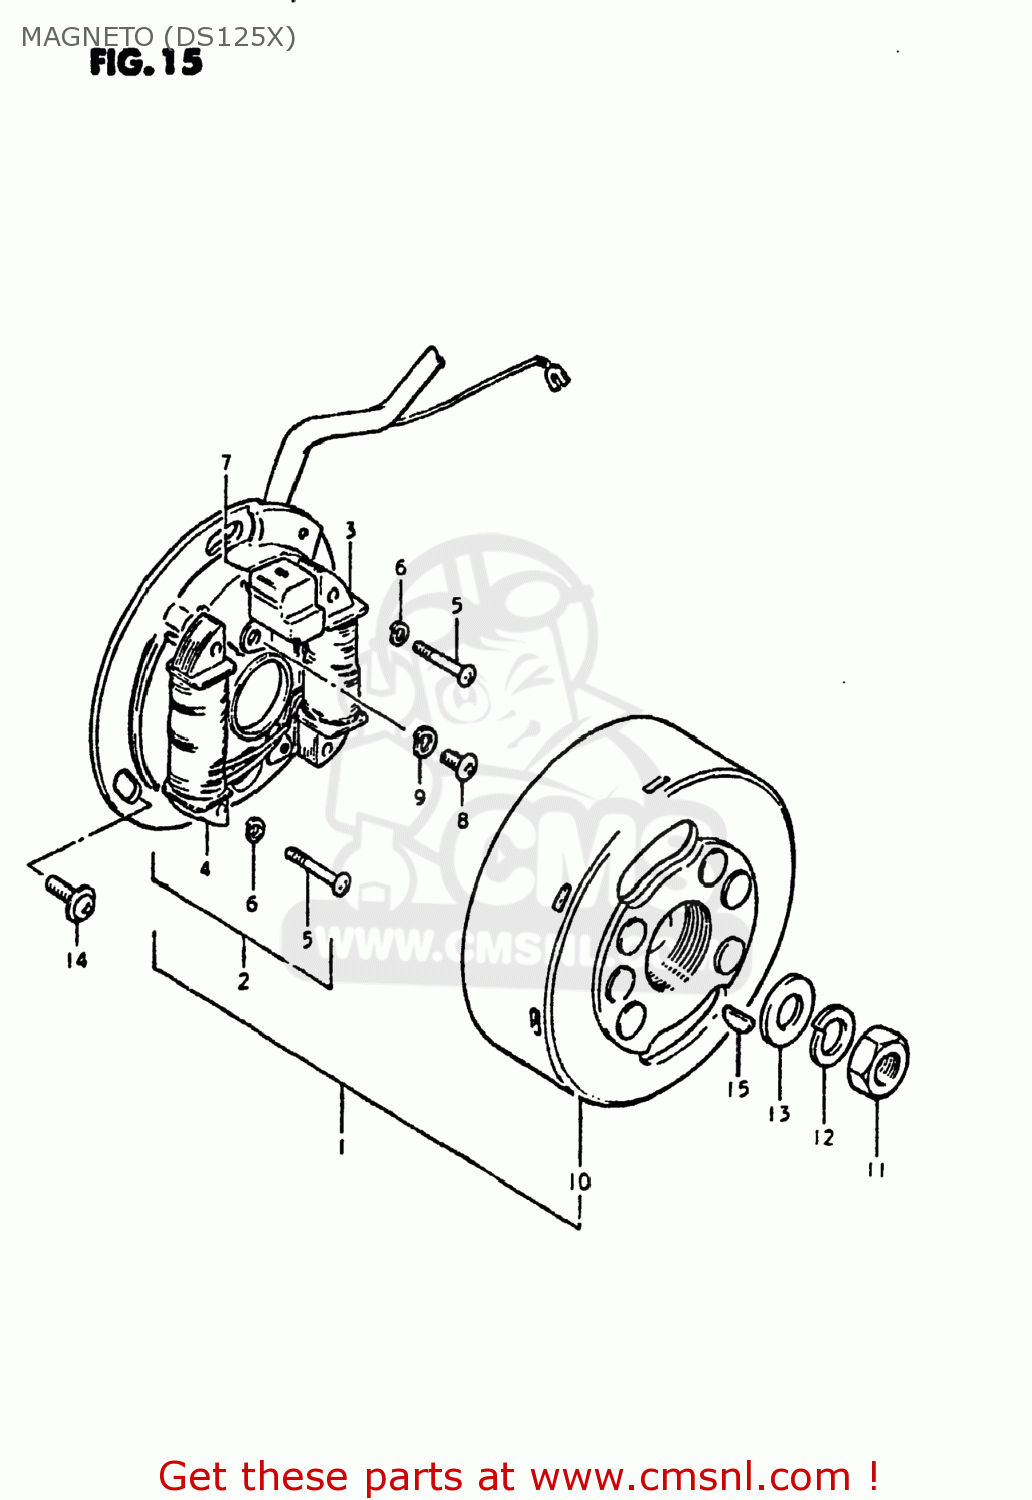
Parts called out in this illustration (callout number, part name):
1	MAGNETO ASSEMBLY
2	STATOR ASSEMBLY
3	COIL,LIGHTING
4	COIL
5	SCREW
6	LOCK WASHER
7	COIL,PULSER
8	SCREW
9	LOCK WASHER
10	ROTOR,FLYWHEEL
11	NUT (10MM)
12	LOCK WASHER
13	WASHER
14	SCREW(5X14)
15	KEY
